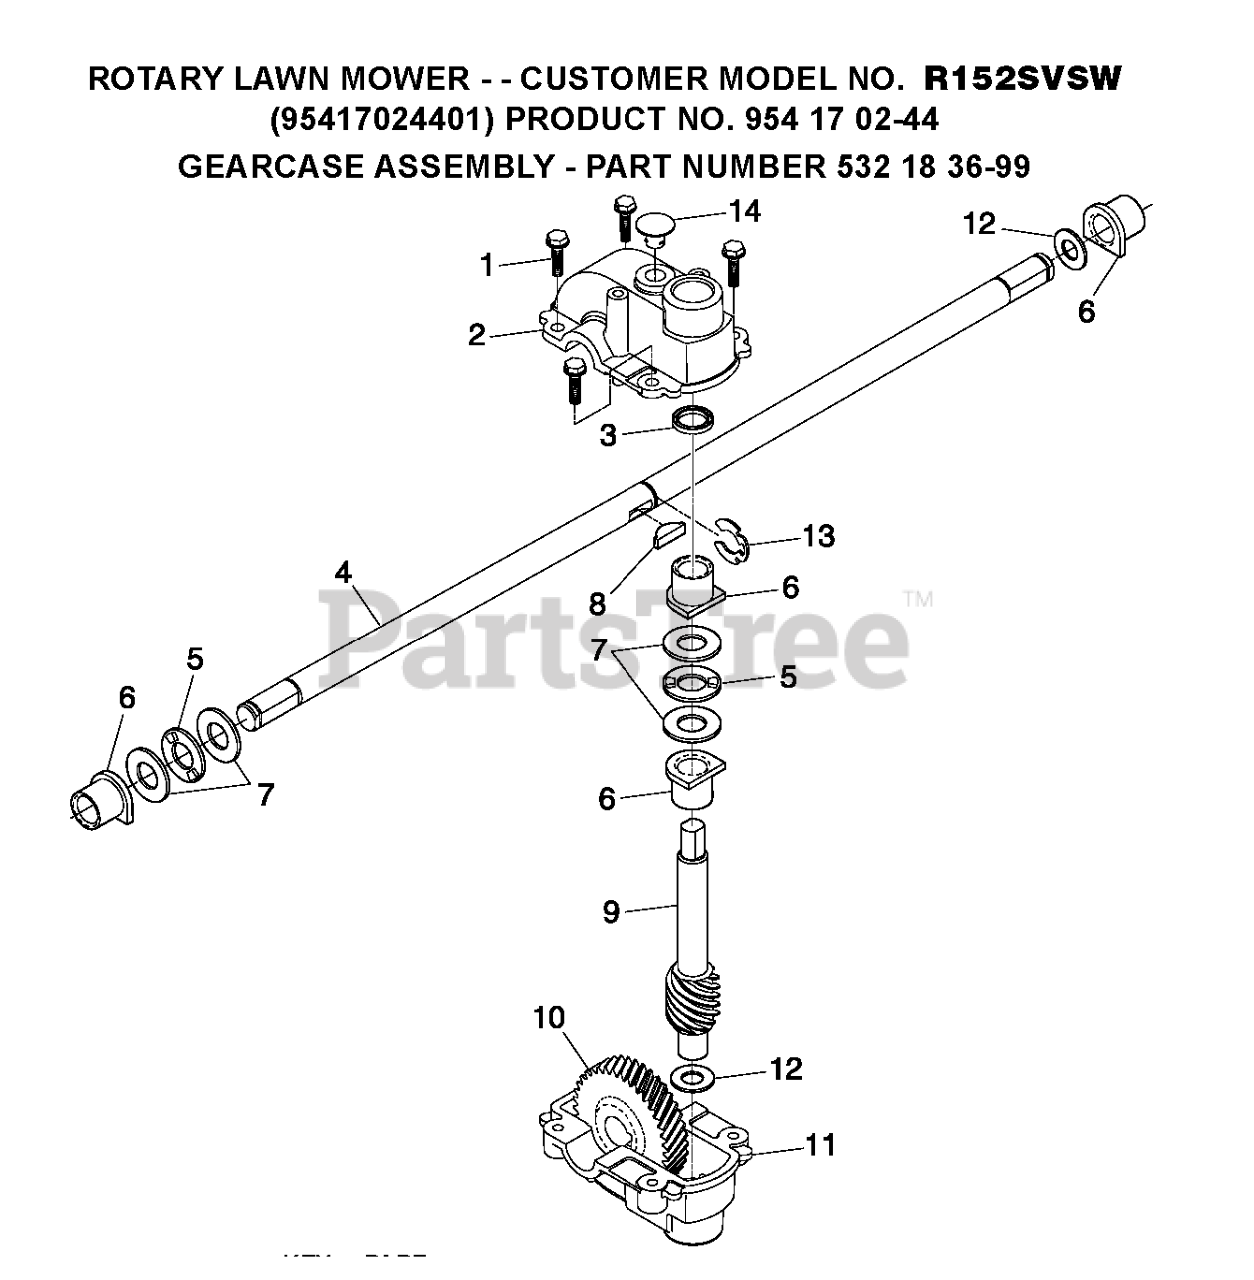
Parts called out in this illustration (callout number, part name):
1	Screw, Hex Washer Head #10-24 x .668
2	GEAR CASE, UPPER
4	SHAFT.DRIVE.HI-VAC.EZ
5	BEARING, NEEDLE, THRUST
7	WASHER, THRUST
8	HI PRO KEY
9	SHAFT.WORM.HI-VAC
10	GEAR, HELICAL
11	GEAR CASE, LOWER
12	THRUST WASHER
14	PLUG.AUGER.GEAR.BOX.SNOW
